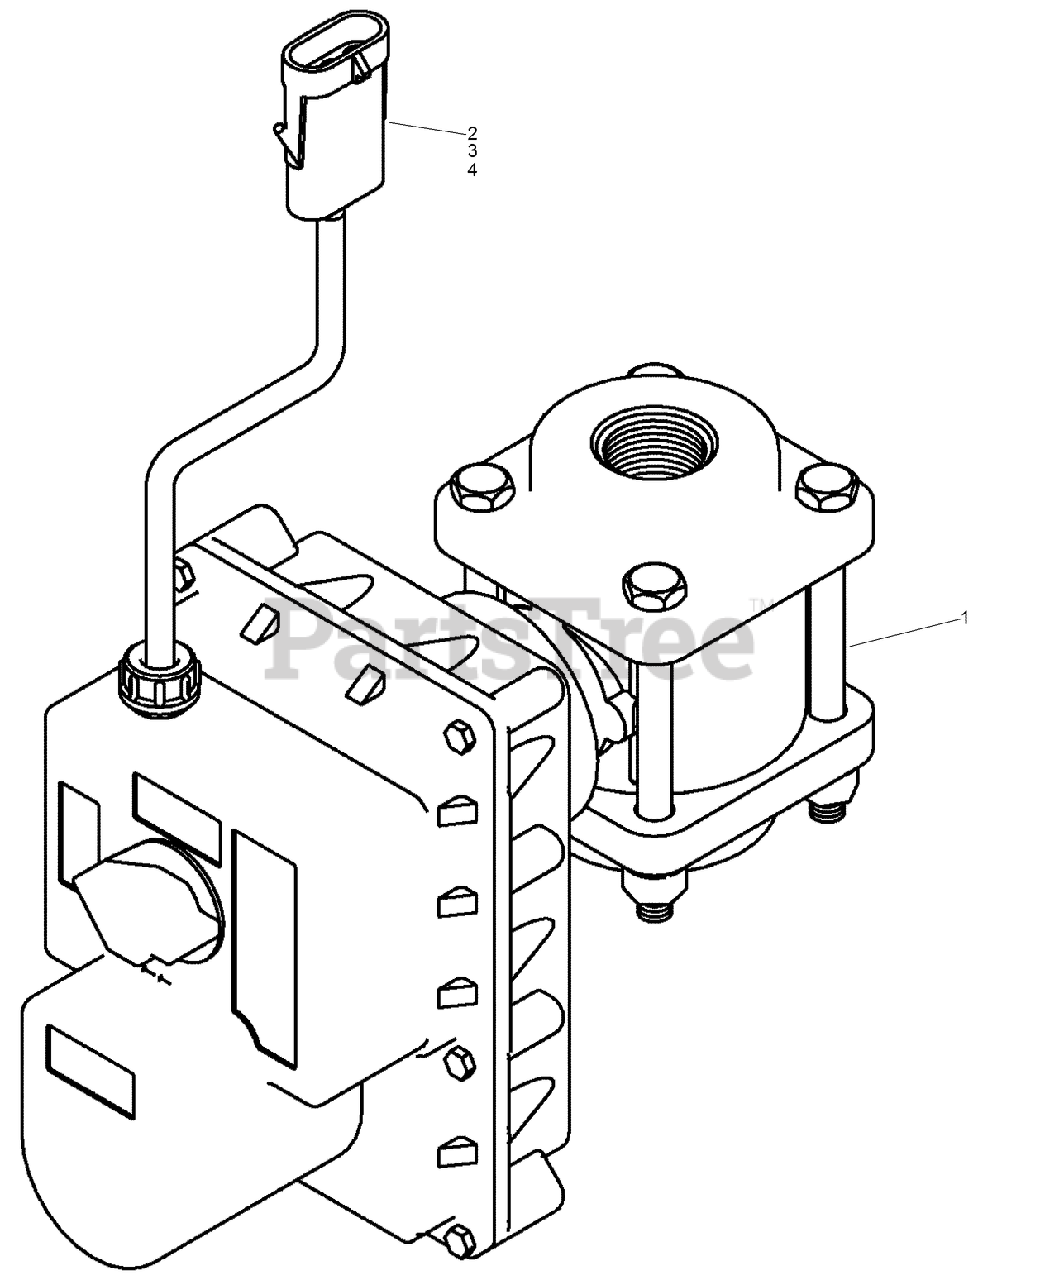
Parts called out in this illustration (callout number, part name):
1	WATER SHUTOFF VALVE ASM
2	CONNECTOR-MALE, 3-WAY (BODY ONLY)
4	TERMINAL-MALE
